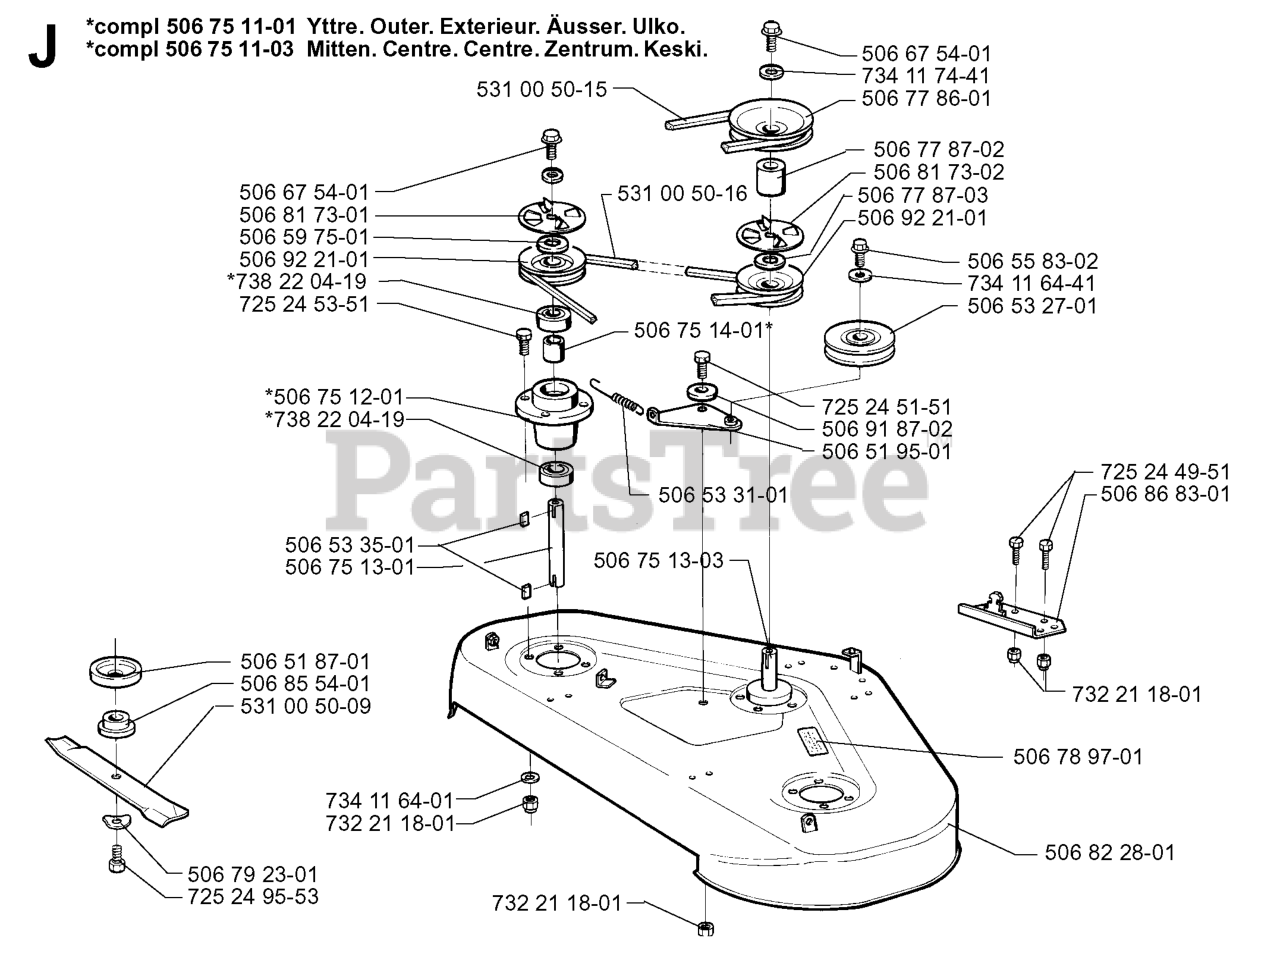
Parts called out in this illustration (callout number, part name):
2	MUFFLER.TWIN.CYL.LOW.TONE
9	KEEPER.BELT.ENGINE.4.2
11	CLUTCH.ELECTRIC.LT.48"*
12	PULLEY.ENGINE.TUFFTORQ
15	TANK.FUEL.SIDE-FILL.3.NON-EPA
18	CAP.FUEL.TANK.3"GREY
20	CONTROL THROTTLE/CHOKE
21	SCREW.#10 X 0.750.BOS
28	LINE.FUEL.64"REAR.EMIS
29	KIT.SPARK ARRESTOR 794945 B&S
37	HOSE CLAMP
42	LOCKWASHER
45	NUT
62	RP SHIELD HEAT MUFFLER
69	GASKET.MUFFLER
70	RP.EXHAUST.TUBE.LH.BS/TWIN
71	EXHAUST.TUBE.RH.BS/TWIN
79	SCREW.SOCKET.HEAD.5/16-18
84	SCREW.3/8-16
85	BOLT HEX 7/16-20X4-1/4"
87	BOLT 5/1618UNC X 3/4 W/ SEMS
90	SCREW 3/8-16X1
91	BUSHING.1.375OD
116	RP KNOB SOFT TOUCH
